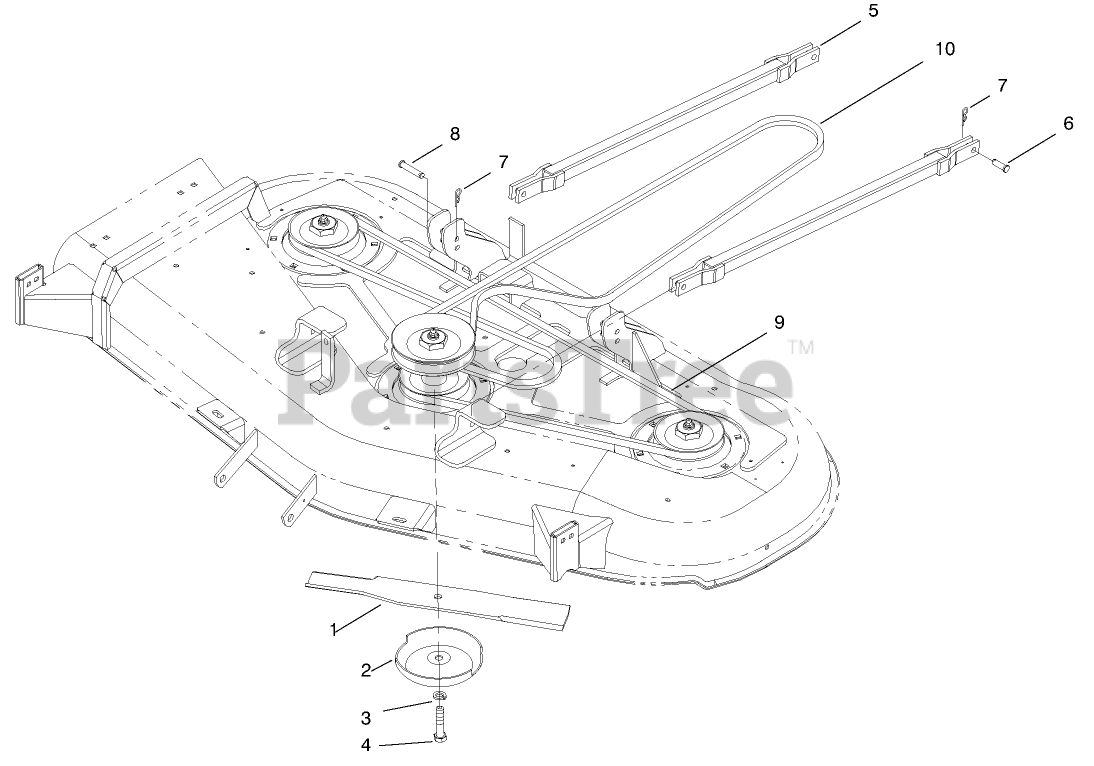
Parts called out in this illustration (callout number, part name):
1	Blade
1	BLADE
2	CUP-SCALP, ANTI
3	WASHER-LOCK
4	SCREW-BLADE
5	Bar-Stabilizer
6	CLEVIS PIN3/8X1 1/4
7	HAIRPIN
8	CLEVIS PIN
9	V-BELT
10	V-BELT, 52" DECK
